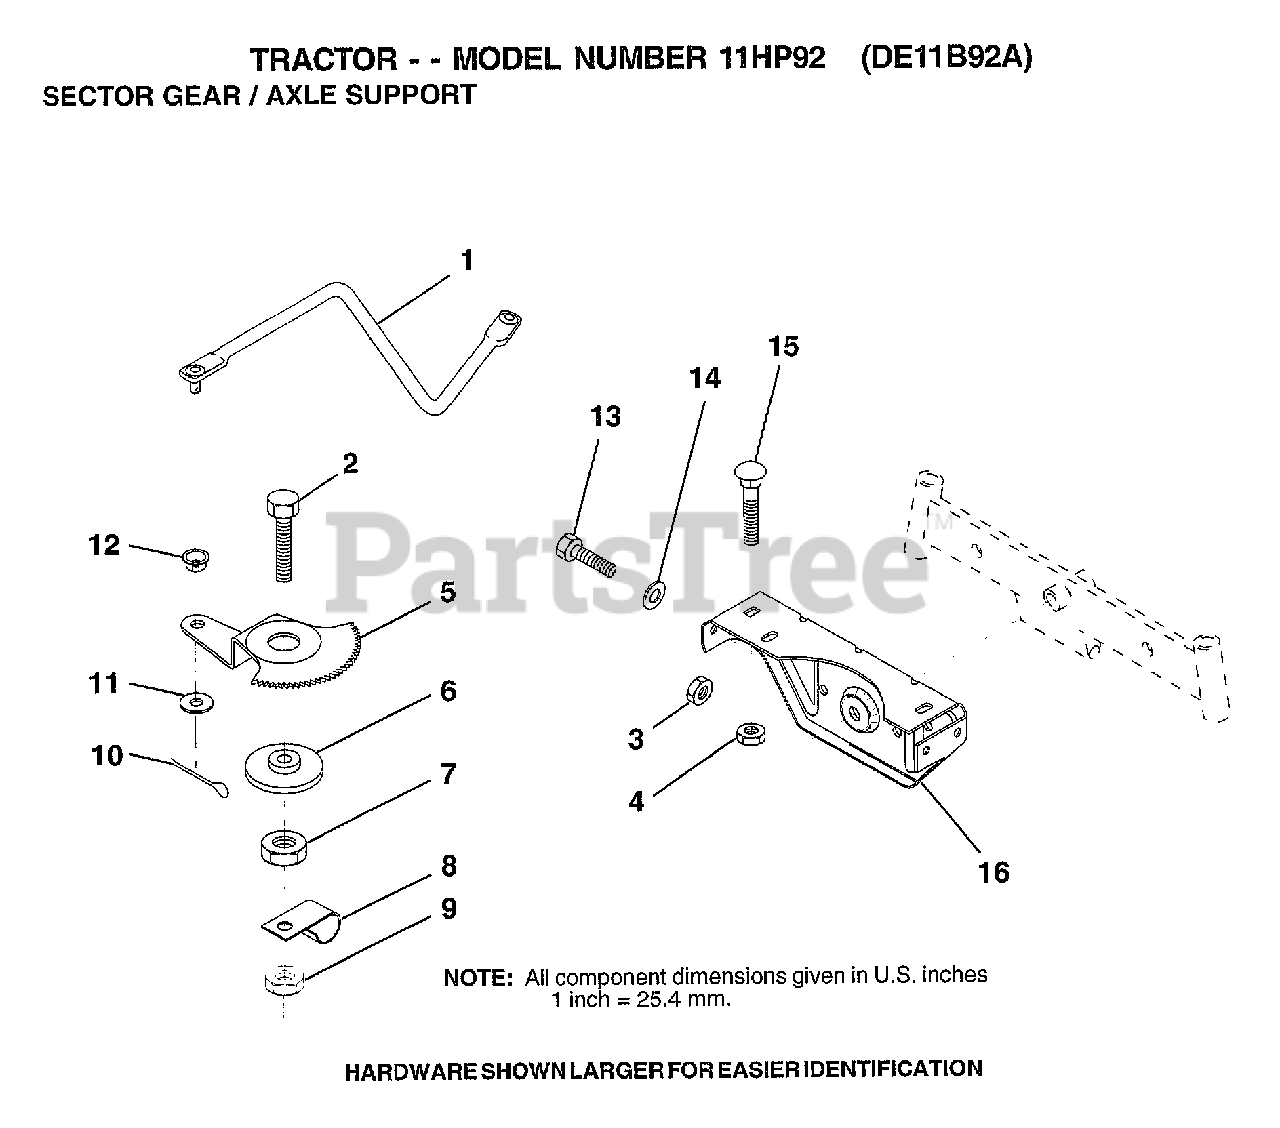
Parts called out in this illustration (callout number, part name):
1	DRAG LINK
2	"BOLT,HEX"
5	GEAR SECTOR
6	BUSHING
7	NUT
8	CLIP INSULATOR
9	NUT LTV
10	COTTER PIN
11	WASHER
12	BUSHING.DRAGLINK
13	BOLT
14	WASHER
15	BOLT
16	SUPT AXLE FRONT
